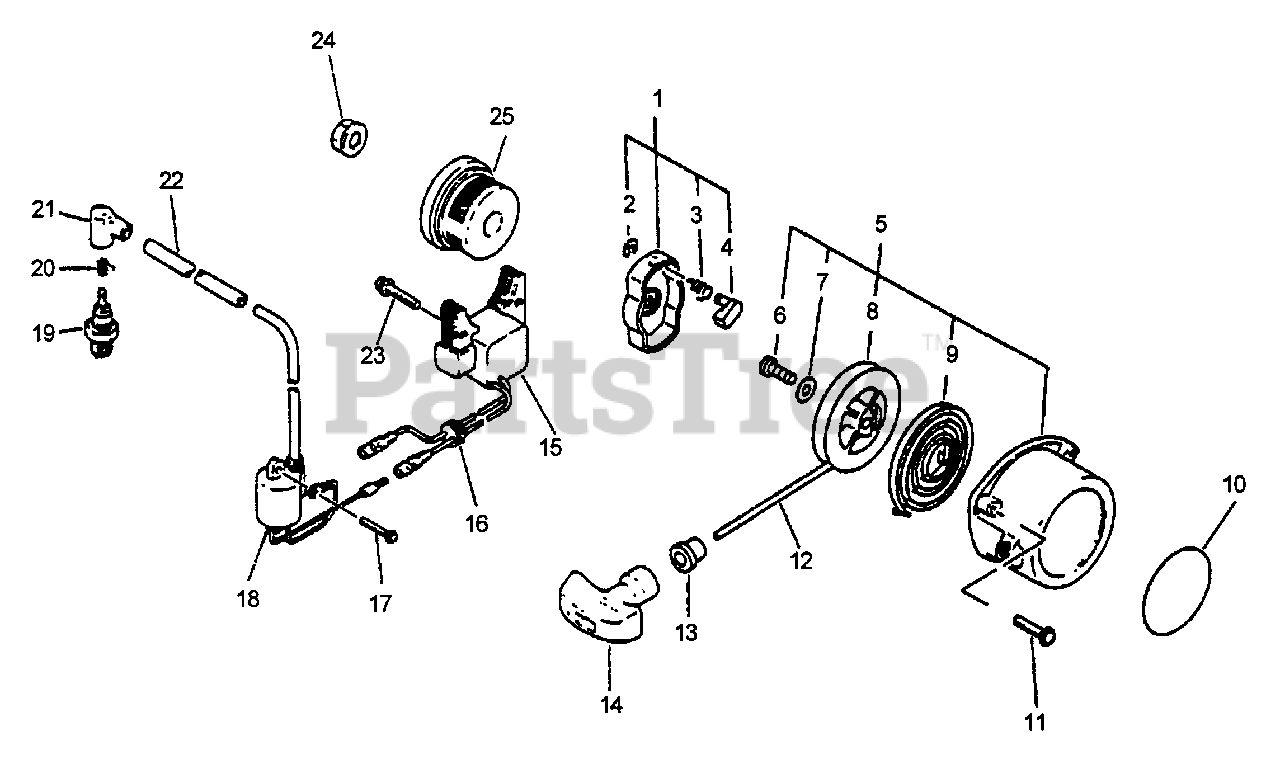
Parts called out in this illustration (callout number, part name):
1	STARTER PAWL ASSY
2	RING, RETAINING - 4
3	SPRING, RETURN
4	PAWL, STARTER
5	STARTER ASSY
8	REEL, ROPE
9	SPRING, REWIND
10	LABEL - ECHO
11	SCREW - 5X16
12	ROPE, STARTER - 4X950
13	GUIDE, ROPE
14	GRIP, STARTER
15	COIL, IGNITION
17	SCREW - 4X25
18	COIL, IGNITION
19	SPARK PLUG -- BM-6A
20	TERMINAL, SPARK PLUG CAP
21	CAP, SPARK PLUG
23	SCREW - 5X25
24	NUT - 10 -- FLANGE
25	FLYWHEEL
